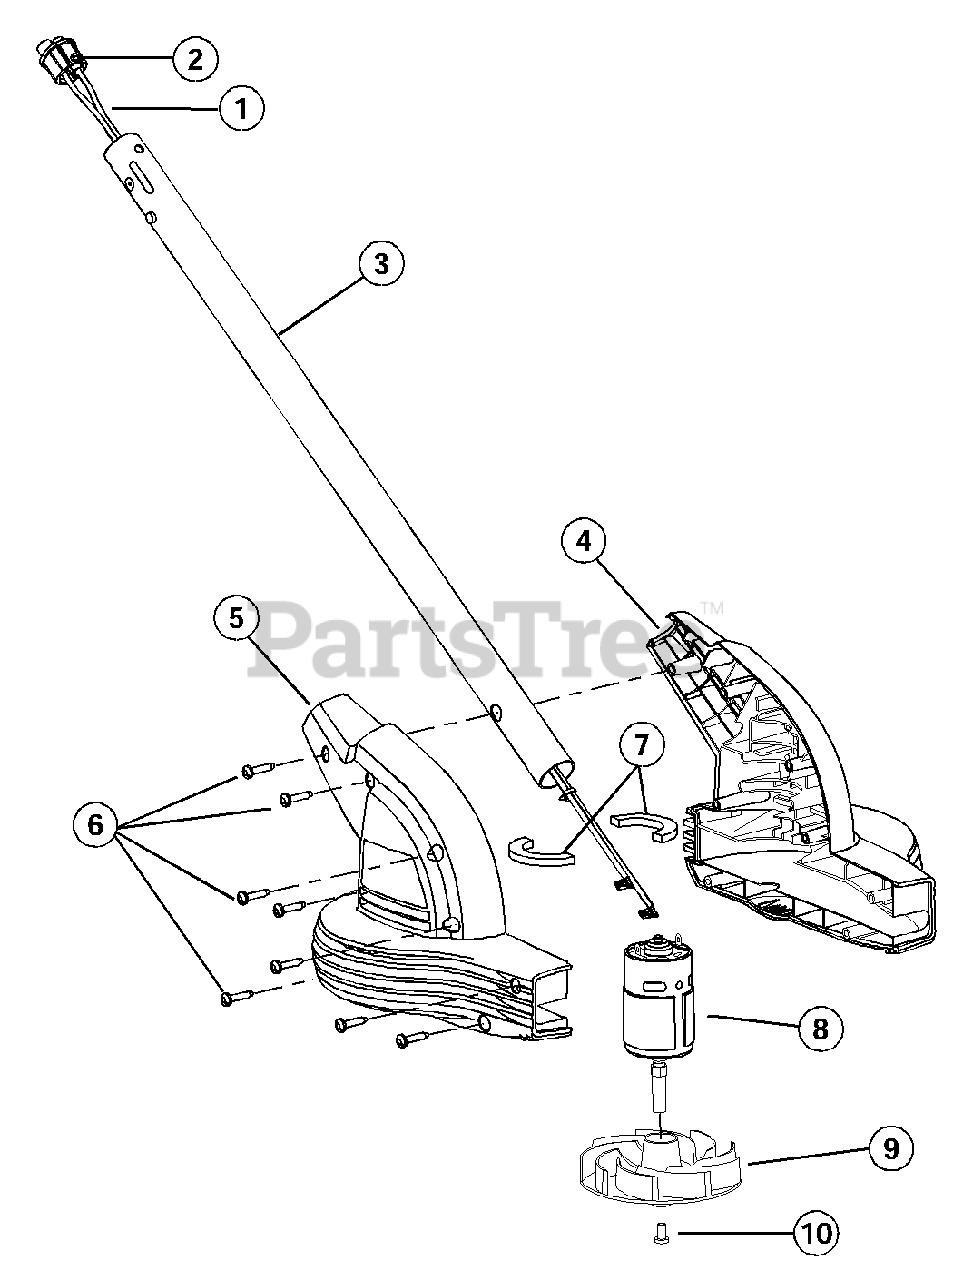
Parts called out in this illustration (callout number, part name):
1	Wiring Harness
2	Plug Connector
3	Lower Motor Wire Tube
4	Left Motor Housing
5	Right Motor Housing
6	Motor Housing Screw
8	Motor with Shaft
9	Impeller
